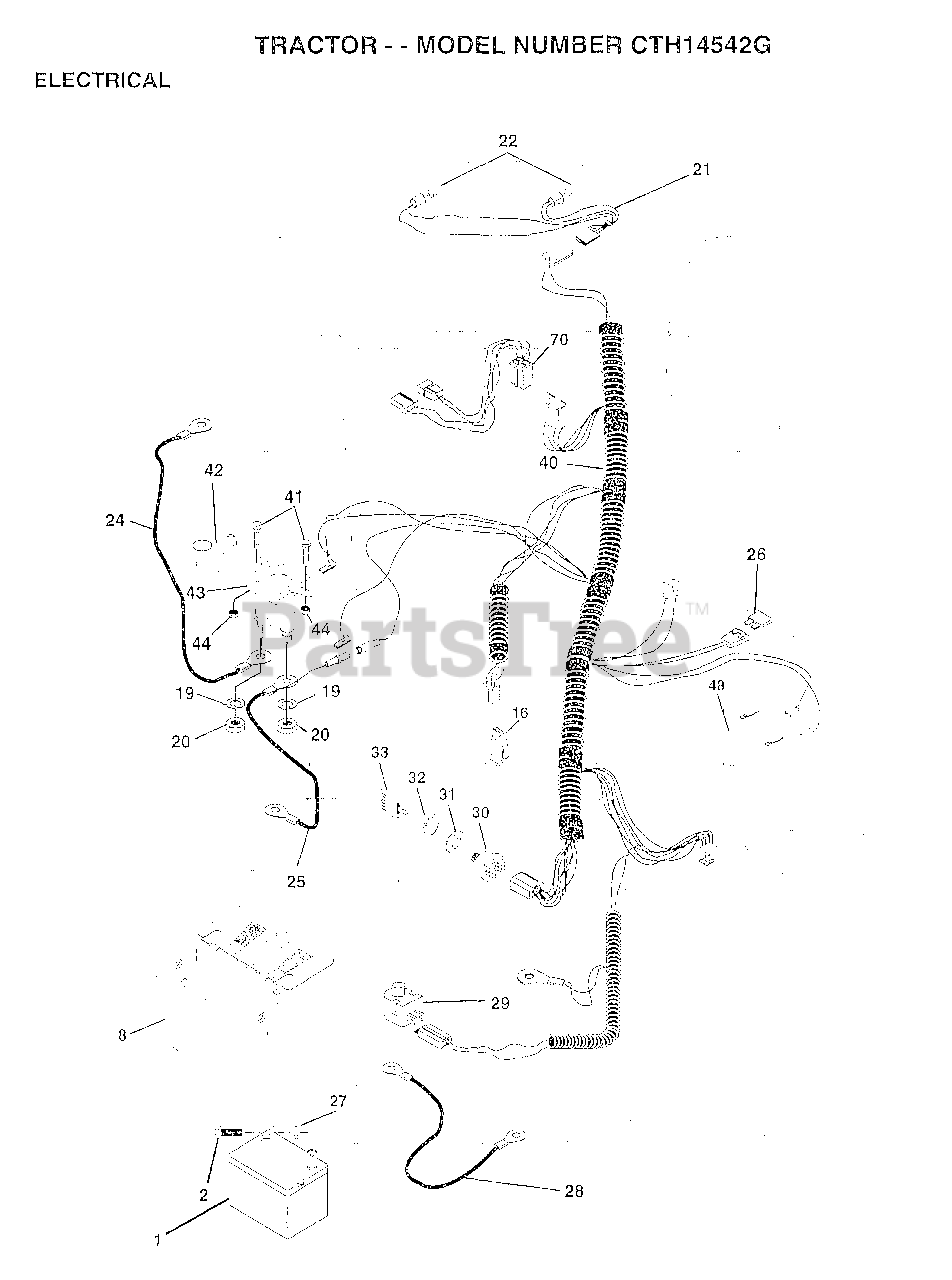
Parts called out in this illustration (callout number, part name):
2	BOLT LT
8	"CASE,BATTERY.MECH"
16	SWITCH INTERLOCK
20	NUT
21	"HARNESS,LIGHT SOC"
22	HEADLAMP BULB
24	CABLE.BTRY.6GA.38
25	CABLE.BTRY.6GA.RD
26	FUSE HYT
27	NUT
28	CABLE T
29	SWITCH SEAT
30	SWITCH IGN 4POS
31	NUT IGNITION
32	COVER KEY SWITCH
33	KEY
40	HARNESS IGNITION
41	BOLT HXHD FIN
44	NUT HXKEP 1/4X20
48	ADAPTER AMMETER
70	HARNESS.ENG.DUAL
